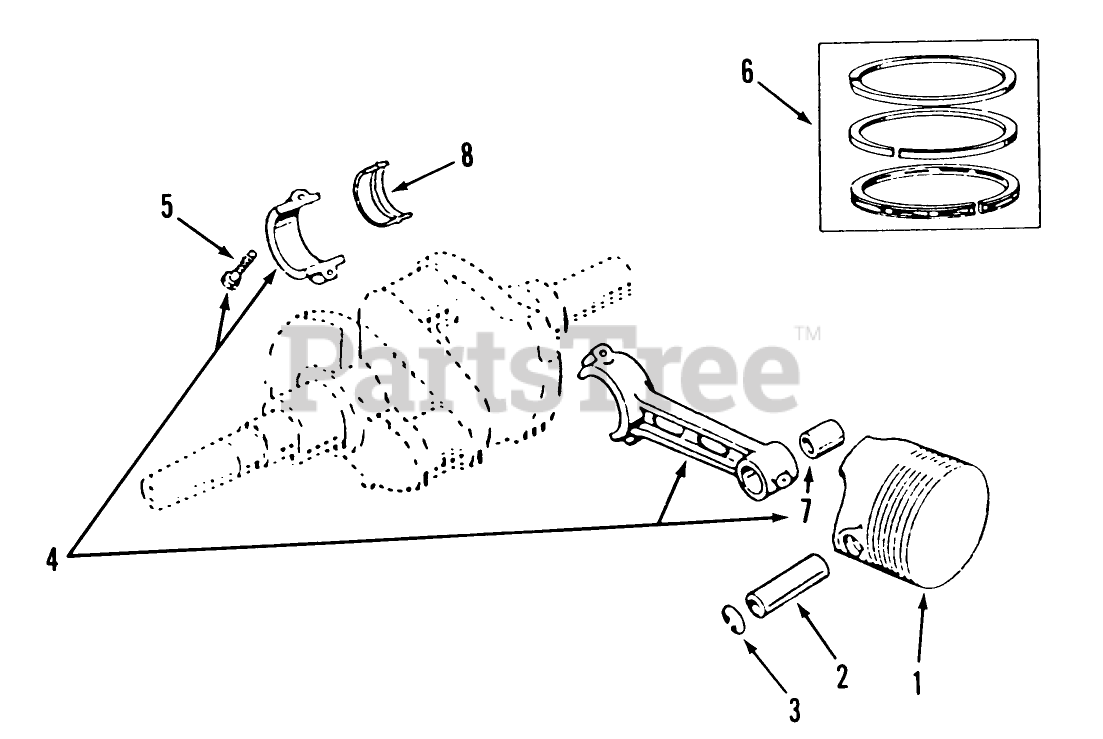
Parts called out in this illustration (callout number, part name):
1	Piston Pin (Incl. Pin Retaining Ring) Spec. D Engine
2	PIN - PISTON
4	ROD-CONNECTING
5	BOLT-PLACE
6	Set-Piston Ring Spec. D Engine
7	BUSHING-PISTON PIN
8	Bearing-Connecting Rod, Half
